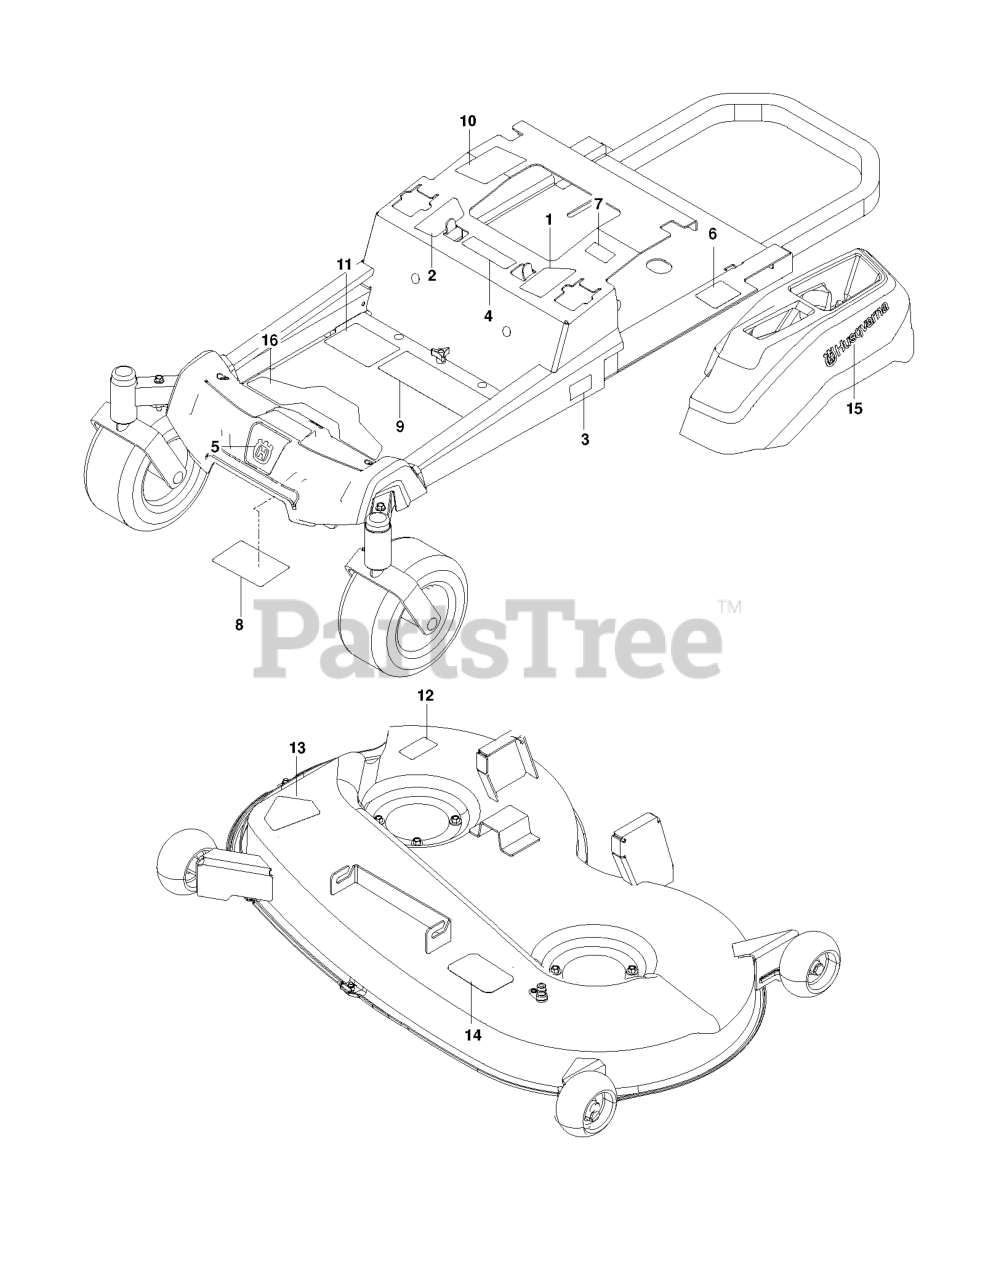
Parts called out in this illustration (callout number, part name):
1	DECAL.ZTR.RZ.THRTL/PRKBRK.V2.L
2	DECAL.ZTR.RZ.THRTL/PRKBRK.V2.R
3	DECAL.ZTR.SIDERAIL.Z246.HUSQ
4	EURO DECAL-BATTERY WARNIN6
5	DECAL.BADGE.55MM.CROWNH.HUSQ
6	DECAL, DO NOT TOW
7	DECAL, EXITING MOWER
8	DECAL, SERVICE
9	DECAL ZTR WARNING DECAL DECAL.
10	DECAL, CUSTOMER RESPNSIBILITY
11	DECAL.ZTR.STARTINSTRCT.CHOKE15
12	DECAL.DECK.6MIL./DEF.SHLD.WARN
13	DECAL, DECK DEFLECTOR, WARNING
14	DECAL, BELT ROUTING
15	DECAL.HUSQVARNA.210MM
16	PAD.RZ.FOOTREST.PLATE
